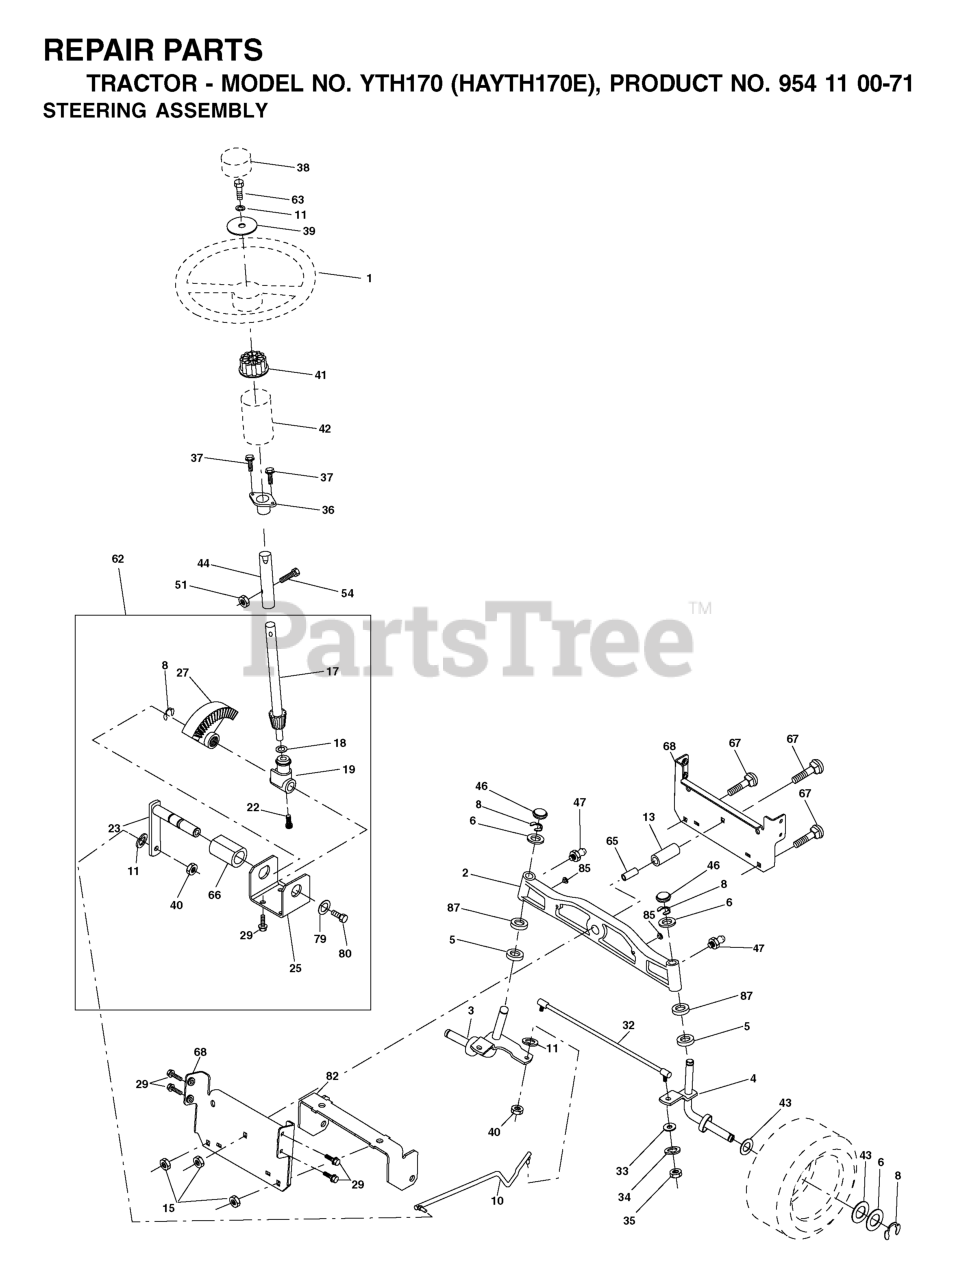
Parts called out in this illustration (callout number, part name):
1	STEERING WHEEL
2	AXLE
3	SPINDLE.ASM.LH.15"TIRES
4	SPINDLE.ASM.RH.15"TIRES
5	THRUST WASHER
10	DRAGLINK.15".TIRES
11	WASHER, LOCK 3/8
13	TUBE, PIVOT AXLE
15	NUT
17	SHAFT ASM STEERING
18	THRUST WASHER
19	STEERING SHAFT SUPPORT
22	SCREW.HX.WSH.HD
23	SHAFT ASSY PITTMAN
25	BRACKET STEERING
27	GEAR.SECTOR
29	SCREW 3/8-16X3/4
32	TIE ROD
33	WASHER M
34	WASHER.LOCK.HVY.HLCL.SPR.5/16
35	NUT, CROWNLOCK
36	BUSHING, STEERING
37	SCREW.TT.#10-32X.5.3/8.FLANGE
38	INSERT,STR WHEEL
39	WASHER 13/32 X 2-3/8 X 12GA
40	GRIPCO NUT
41	ADAPTER LT
42	BOOT STEERING
44	EXT SHAFT STEERING
46	CAP.SPINDLE.BLACK
47	ZERK M
51	NUT.71038.31-18.HEX.NYLOCK
54	BOLT.5/16-18X1-1/4 FULL.THREAD
62	STEERING KIT
63	BOLT
65	SPACER BRACE AXLE
66	BEARING ARM
67	BOLT
68	BRACE.AXLE.15"TIRES
79	WASHER
80	BOLT.HX.NYLON3/8-16X
82	BRACKET
85	FASTENER.XMAS.TREE
87	WASHER, FLAT .781 X 1 1/2"
